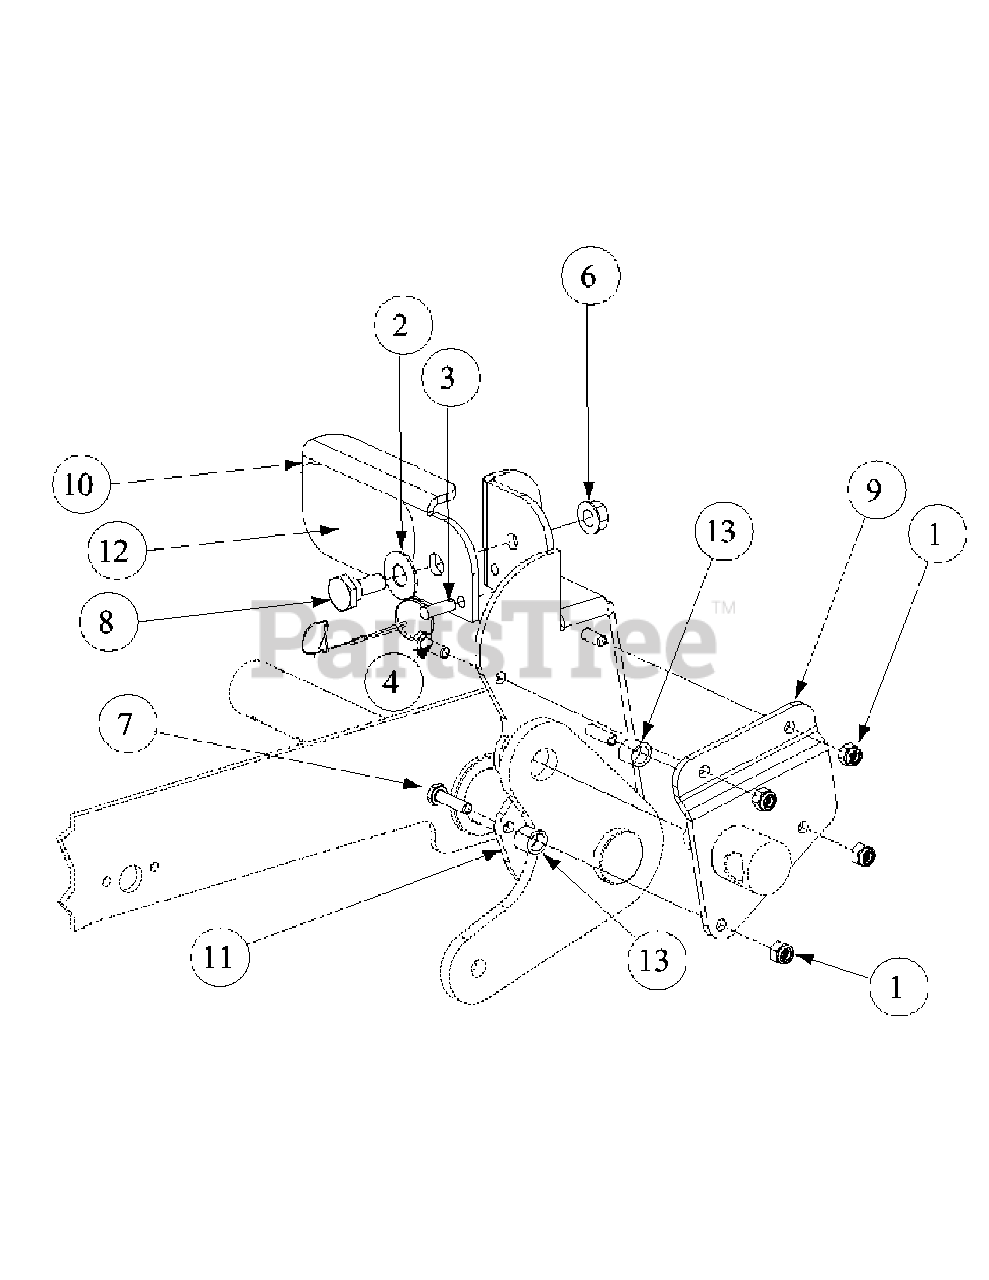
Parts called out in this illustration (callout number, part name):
1	Lock Nut, Nylon Insert, 1/4-20
2	Washer, 1/2 x 1 Shim
3	Detent Pin, w/12" Lanyard
4	Hex Cap Screw, 1/4-20, .75
6	Hex Nut, Flange Lock 3/8-16
7	Hex Cap Screw, 1/4-20, 1.00
8	Shoulder Screw, .50x.27 Lg., 3/8-16
9	Foot Lift Backup Pedal
10	Deck Foot Pedal Lift
11	Deck Foot Pedal Lift Holder
12	Deck Foot Lift Pad
13	Turnbuckle Sleeve
